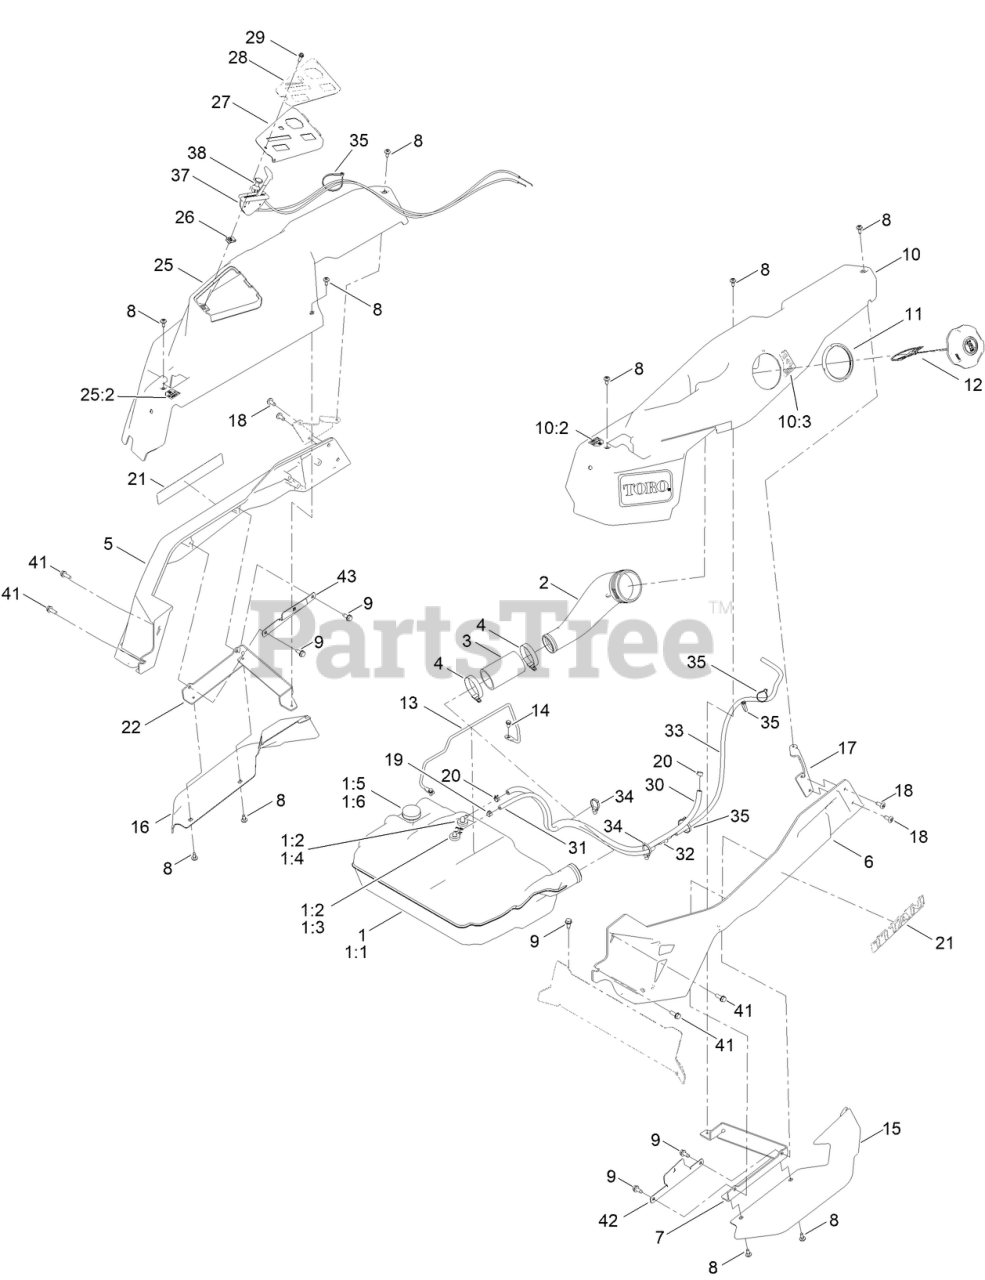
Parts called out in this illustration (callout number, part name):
1	TANK-FUEL, ASM
1:1	TANK-FUEL
1:2	BUSHING
1:3	FITTING-ELBOW 90
1:4	FITTING - PICKUP, FUEL
1:5	GROMMET-FUEL
1:6	REMOTE GAUGE ASM
2	NECK-FILLER, FUEL
3	HOSE-FILLER, FUEL
4	CLAMP-HOSE
5	CAST-TUBE, RH [RED]
6	CAST-TUBE, LH [RED]
7	MOUNT-POD BRACKET LH
8	SCREW-SHOULDER
9	SCREW-HWHTF
10	POD ASM - LH W/DECALS
10:2	DECAL-CONTROL LEVER, LH
10:3	DECAL-FUEL FILL
11	RING-RETAINING
12	CAP-FUEL, RATCHETING
13	ROD-HOLD DOWN
14	SCREW-HWH
15	FENDER-TIME CUTTER, LH
16	FENDER-TIME CUTTER, RH
17	BRACKET-REAR POD, LH
19	CLAMP-HOSE
20	CLAMP-HOSE
21	DECAL-TITAN
22	BRACKET-MR SPRING
25	POD ASM - RH , MR W/DECALS
25:2	DECAL-CONTROL LEVER, RH
27	PANEL-CONTROL
28	DECAL - CONTROL PANEL
29	SCREW-HWHTF
30	HOSE-FUEL
31	HOSE-FUEL
32	ADAPTER ORIFICE
33	HOSE-LP
34	CLIP-TIE
35	TIE-CABLE
37	CABLE-THROTTLE
38	CABLE-CHOKE
41	SCREW-TAPTITE
42	BRACKET-ALIGNMENT, POD LH
43	BRACKET- ALIGNMENT, POD RH MR
